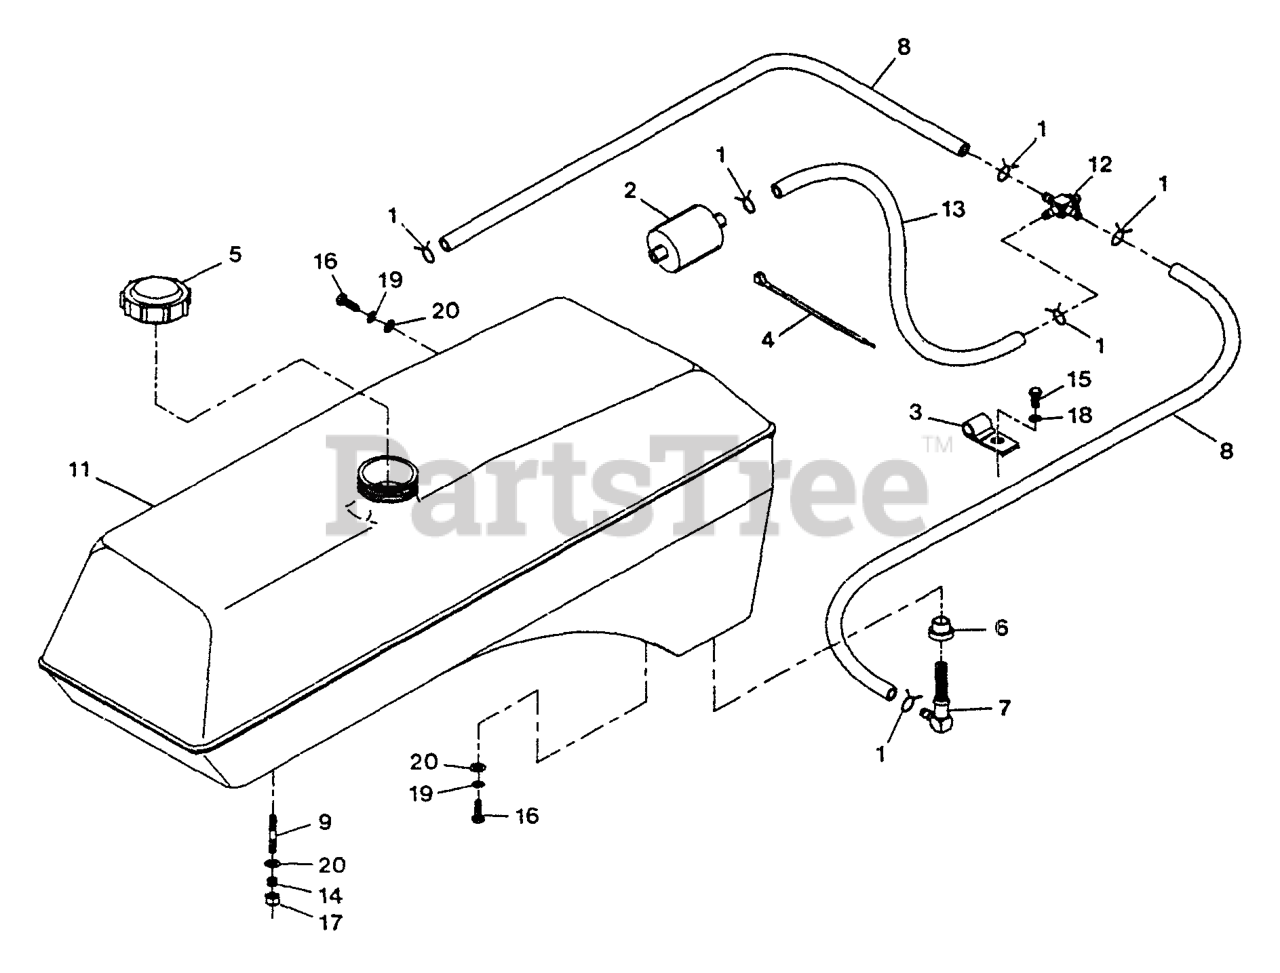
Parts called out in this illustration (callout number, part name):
2	Fuel Filter
3	CLIP-LOOM
4	TIE-PLASTIC
5	CAP-FUEL
7	ELBOW-TANK, FUEL
8	HOSE-FUEL
9	STUD
12	VALVE-FUEL
14	SPRING-TANK, FUEL
18	WASHER-LOCK
19	WASHER-LOCK
